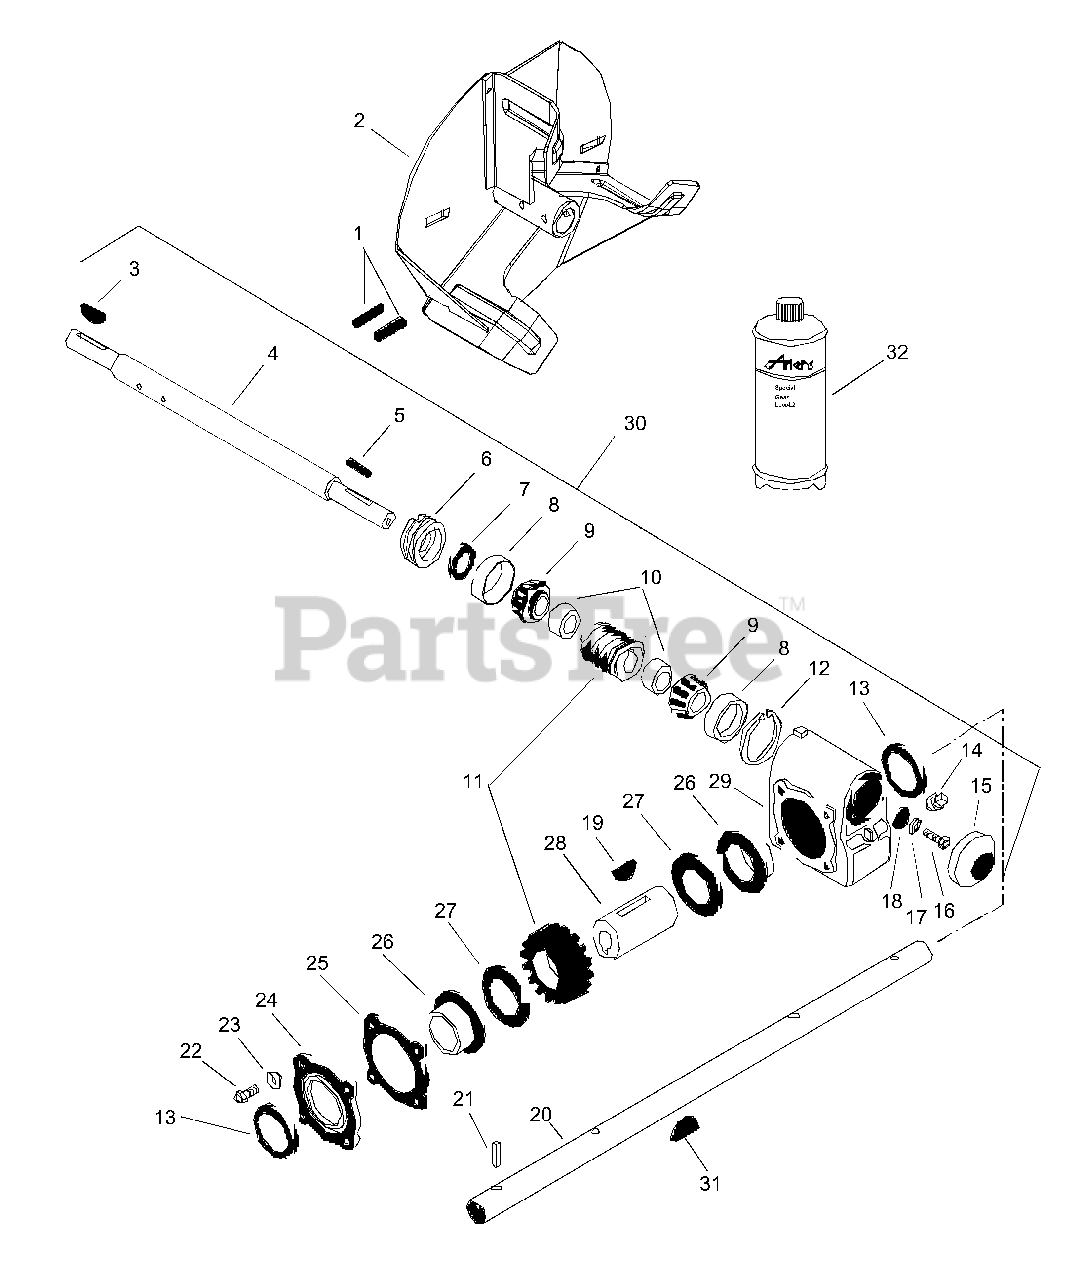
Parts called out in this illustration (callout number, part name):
1	PIN-ROLL .313X1.75
2	IMPELLER - 1 ID X 14 OD
3	KEY-WDRF .188X.875X.375 SAE11
4	SHAFT, WORM - 1.00 DIA.
5	KEY-SQ .188X1.0X.188 SAE 8630
6	ADJUSTMENT PLUG - 1" SHAFT
7	SEAL 1.000X1.312X.150
8	BRG-CUP 1.781X.475
9	BRG-CONE .750X.61
10	BSHG, SPCR .755X1.12X.50 PM
11	WORM & GEAR SERVICE ASSEMBLY
12	RG-RTNG-INT 1.781X.062
13	SEAL 1.625X2.125X.250
14	PIPE PLUG
15	DUST CAP
16	@BLT-HEX .31-18X.75 GR5 YWZC
17	WSHR-LK .312X.097 HVY YWZC
17	@WSHR-LK .31X.078 REG YWZC
18	WSHR-FL-STL .328X1.0X.094 YWZC
19	KEY-WDRF .25X.875X.375 SAE A
20	SHAFT, 32" RAKE - 1.00 DIA.
21	PIN-ROLL .188X1.50
22	@BLT-HEX .25-20X.75 GR5 YWZC
23	@WSHR-LK-EXT.262X.502X.026YWZC
24	GEAR CASE COVER
26	BSHG-FLG .683X1.87X1.68X2.250
27	WSHR-FL-STL 1.625X2.500X.012
28	GEAR CASE SHAFT
29	GEAR CASE - CAST IRON
30	GEAR CASE, CAST IRON
30	GEAR CASE - CAST IRON
32	ARIENS 16 OZ.BOTTLE OF L2 LUBE
